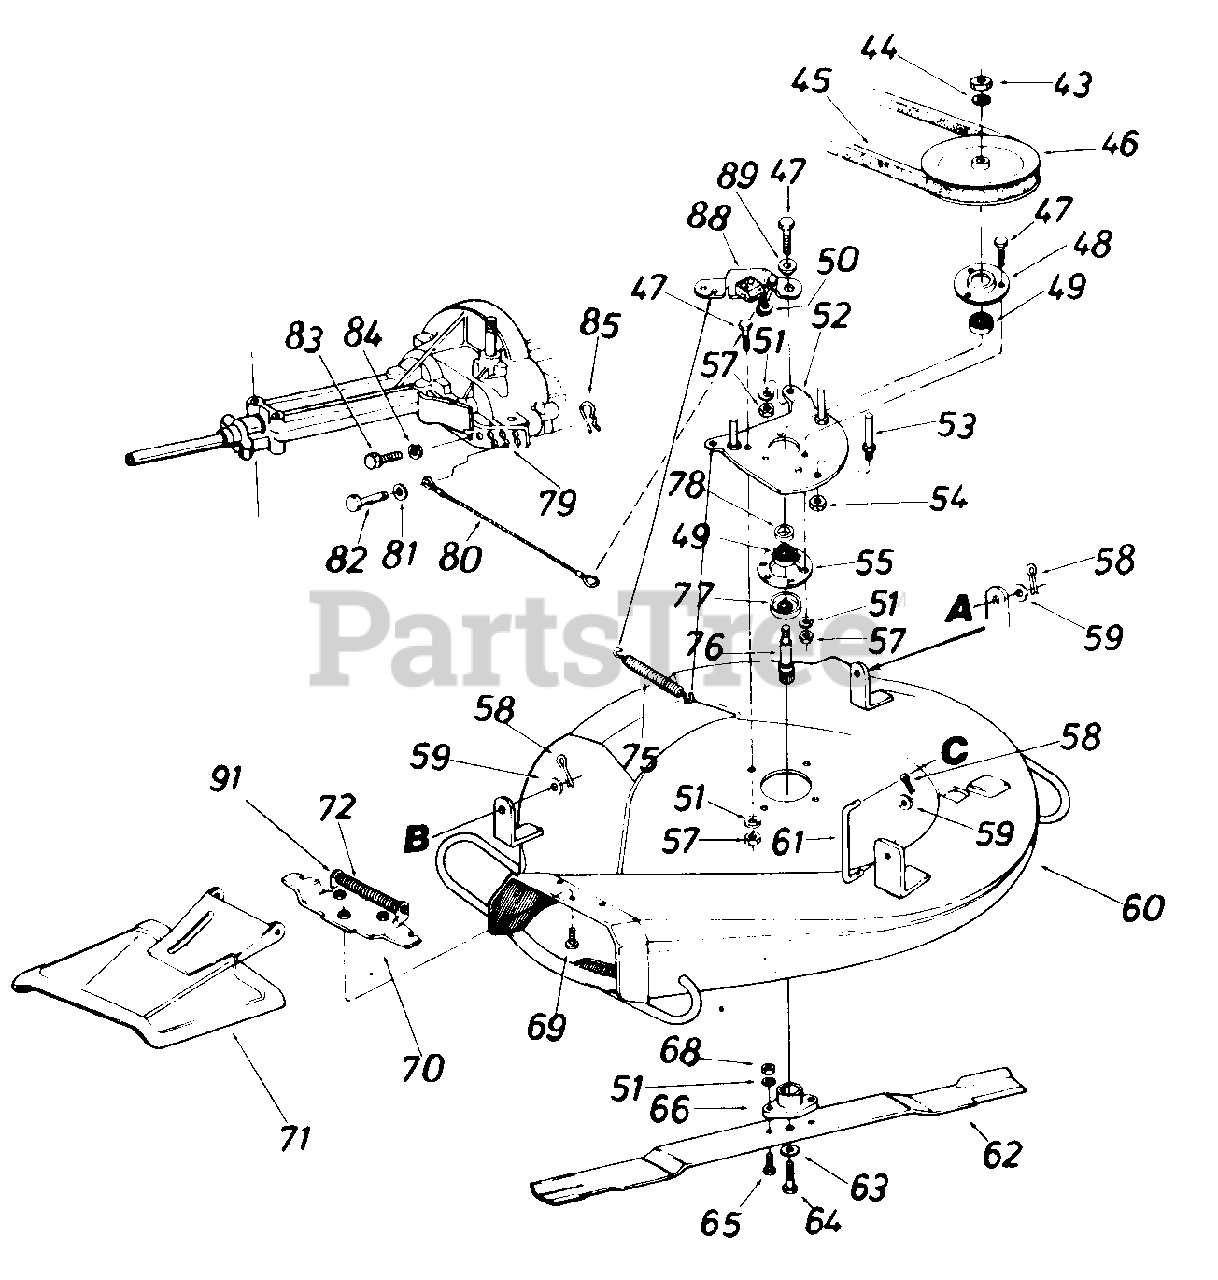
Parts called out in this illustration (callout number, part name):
43	Hex Jam Nut 5/8-18 Thd.
44	Bell-Wash. .63" I.D. x 1.25" O.D.
45	V-Belt 1/2 x 52" Lg.
46	1/2" V-Pulley .625" I.D. x 6.0" O.D.
47	Hex Bolt 5/16-18 x .75"
48	Open Brg. Housing 1.85" I.D.
49	Ball Brg. .787" I.D. x 1.85" O.D.
50	Cap Speed Nut 1/4" Rod
51	L-Wash. 5/16" I.D.
52	Spindle Mtg. Plate
53	Stud 3/8-16 x 3.00" Lg.
54	Hex Jam Nut 3/8-16 Thd.
55	Bearing Housing 1.85" I.D.
57	Hex Nut 5/16-18 Thd.
58	Intern. Cotter Pin 1/2" Dia.
59	Fl-Wash. .385" I.D. x .87"
60	26" Deck Ass'y.
61	Deck Link 3.9" Lg.
62	26" High Lift Blade
63	Bell-Wash. .39" I.D. x 1.38"
64	Hex Bolt 3/8-24 x 1.0"
65	Hex Bolt Spec. 5/16-24 x 1.0" Lg.
66	Blade Adapter
68	Hex Nut 5/16-24 Thd.
69	Hex Wash. S-Tap Scr. 1/4-20 x.50" Lg.
70	Adapter Plate-Chute
71	Chute Cover Ass'y. Comp.
72	Torsion Spring
75	Extension Spring 3.25" Lg.
76	Blade Spindle 4.42" Lg.
77	Bearing Shield
78	Spacer 1.0" O.D. x .35" Lg.
79	Lower Inside Belt Guard
80	Brake Cable 11.75" Lg.
81	Fl-Wash. .281" I.D. x .50
82	Clevis Pin 1/4" Dia. x .53" O.D.
83	Hex Bolt 1/4-20 x .62" Lg.
84	L-Wash. 1/4" I.D.
85	Intern. Cot.-Pin 5/16" Dia.
88	Blade Brake Brkt. Ass'y.
89	Shld. Spacer .27" Lg.
91	Hinge Pin
